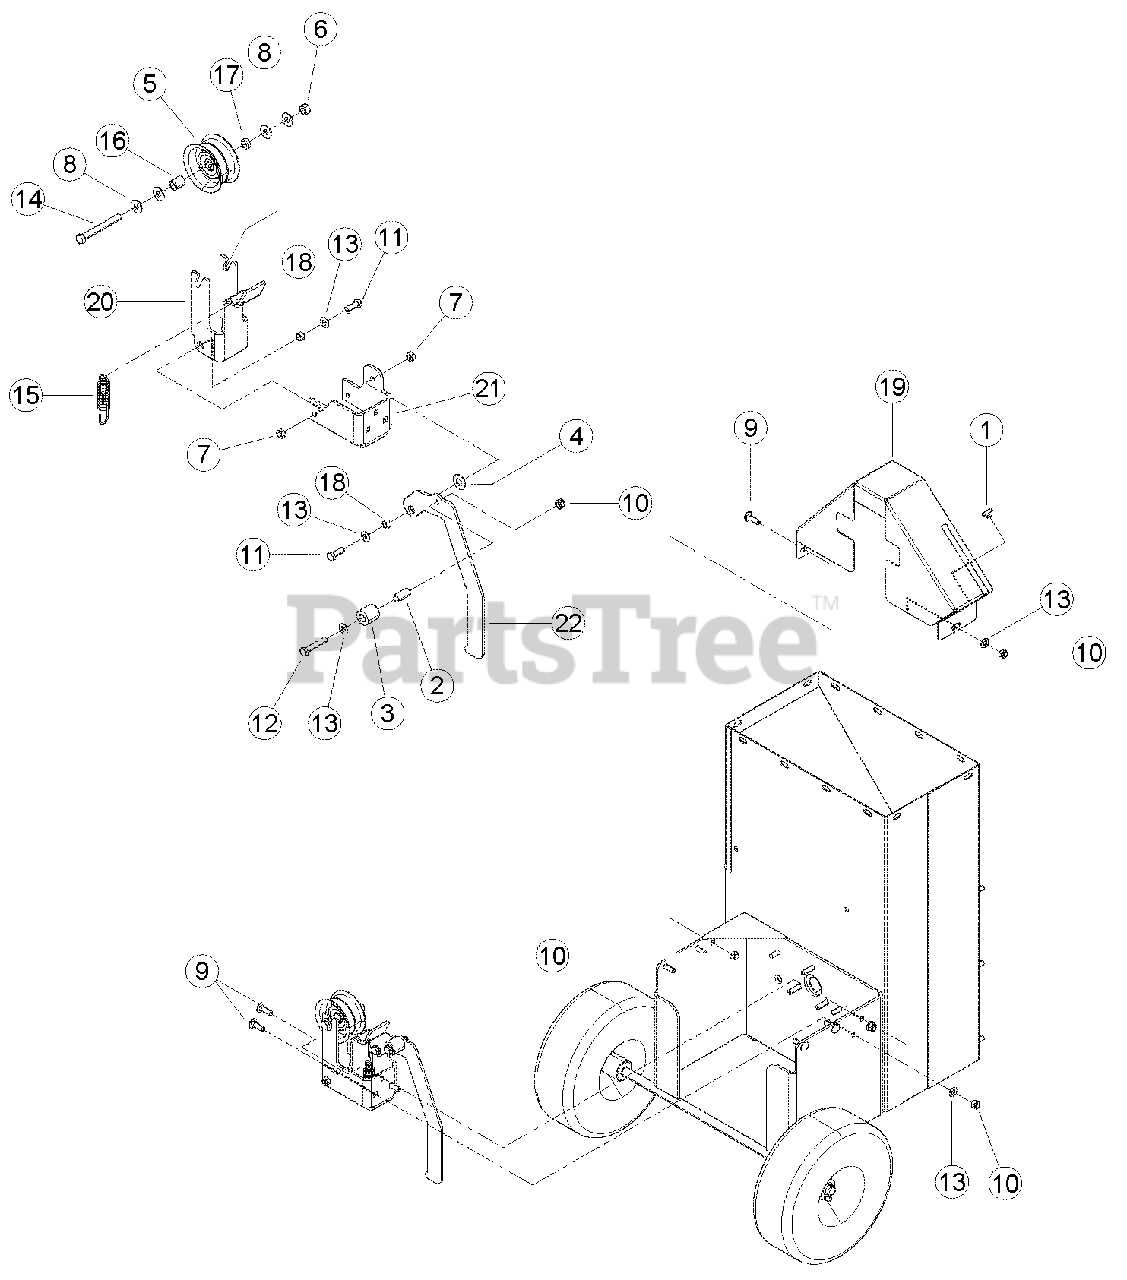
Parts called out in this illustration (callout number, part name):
1	BUMPER, RUBBER
2	SPACER, 0.5 X 1.00
3	ROLLER, 0.5 X 1.00 X 1.00 NYLON
4	NYLON WASHER, 1/2 IN.
5	IDLER, 2.75 X 1.25
6	NUT, 3/8 CENTERLOCK ZP
7	NUT, 5/16 CENTERLOCK NC ZP
8	WASHER, 5/16 FLAT ZP
9	BOLT, 5/16 X 1 CRG GR5 ZP
10	NUT, 5/16 NE NYLOCK ZP
11	BOLT, 5/16 X 7/8 HHCS NC GR5 ZP
12	BOLT, 5/16-18 X 1-3/4 HCS GR5 ZP
13	WASHER, 5/16 SAE FLAT ZP
14	BOLT, 3/8 X 3-1/4 HEX HD GR5 ZP
15	SPRING, 3/4" OD EXTENSION
16	TUBE, 3/4" LONG IDLER SPACER
17	SPACER, IDLER PIVOT
18	SPACER, .50 X .25
19	SHIELD, UPPER
20	BRACKET, IDLER
21	MOUNT, IDLER BRACKET
22	HANDLE, ENGAGEMENT
